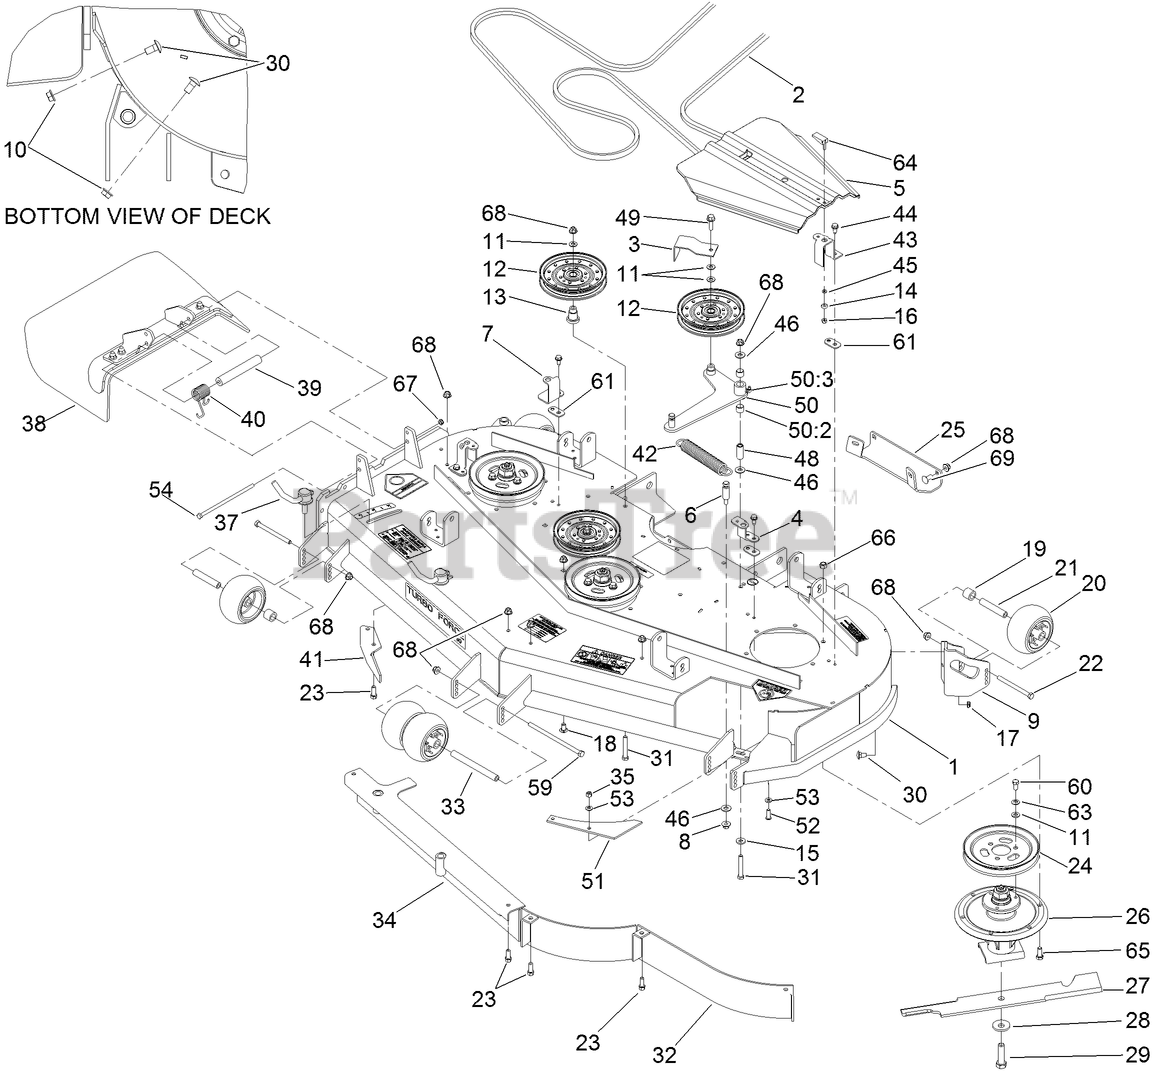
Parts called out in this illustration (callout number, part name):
1	DECK DECAL ASM
2	BELT-V
3	GUIDE-BELT
4	BRACKET-COVER, TALL
5	COVER-BELT
6	PIN-THREADED, SPRING ANCHOR
7	BRACKET-COVER
8	NUT-HF
9	MOUNT-WHEEL, LH
10	NUT-HHF, WHIZ
11	WASHER-FLAT
12	IDLER-PULLEY, FLAT
13	MOUNT-PULLEY
14	BUSHING-LATCH, SWELL
15	WASHER-BELLEVILLE
16	NUT-LOCK, HH
17	NUT-LOCK, NI
18	SCREW-CARR
19	TUBE-SPACER
20	ROLLER-SCALP, ANTI
21	TUBE-SPANNER
22	SCREW-HH
23	SCREW-HWH
24	Pulley
25	Plate-Skid
26	SPINDLE ASM
27	BLADE-HI FLOW
28	Washer-Blade Bolt, Heavy
29	SCREW-BLADE
30	SCREW-CARR
31	SCREW-HH
33	SPACER-WHEEL
35	NUT-LOCK, NI
37	LEVER ASM
38	RUBBER DEFLECTOR ASM
39	SPACER
40	SPRING-TORSION
41	BAFFLE-DISCHARGE
42	SPRING-EXTENSION
43	BRACKET-COVER
44	SCREW-HWHTF
45	WASHER
46	WASHER-FLAT
48	BUSHING
49	SCREW-HHF
50	DECK IDLER ARM ASM
50:2	SLEEVE-BEARING
50:3	FITTING-GREASE, 90 DEG
51	PLATE-TURBO
52	SCREW-HSBH
53	WASHER-SPRING
54	SCREW-HH
59	SCREW-HH
60	SCREW-HH
61	SPACER-BELT COVER
63	WASHER-BELLEVILLE
64	HANDLE-LATCH, SWELL
65	SCREW-HH
66	NUT-LOCK, NI
67	NUT-LOCK, NI
68	NUT-HF, NI
69	SCREW-CARR
